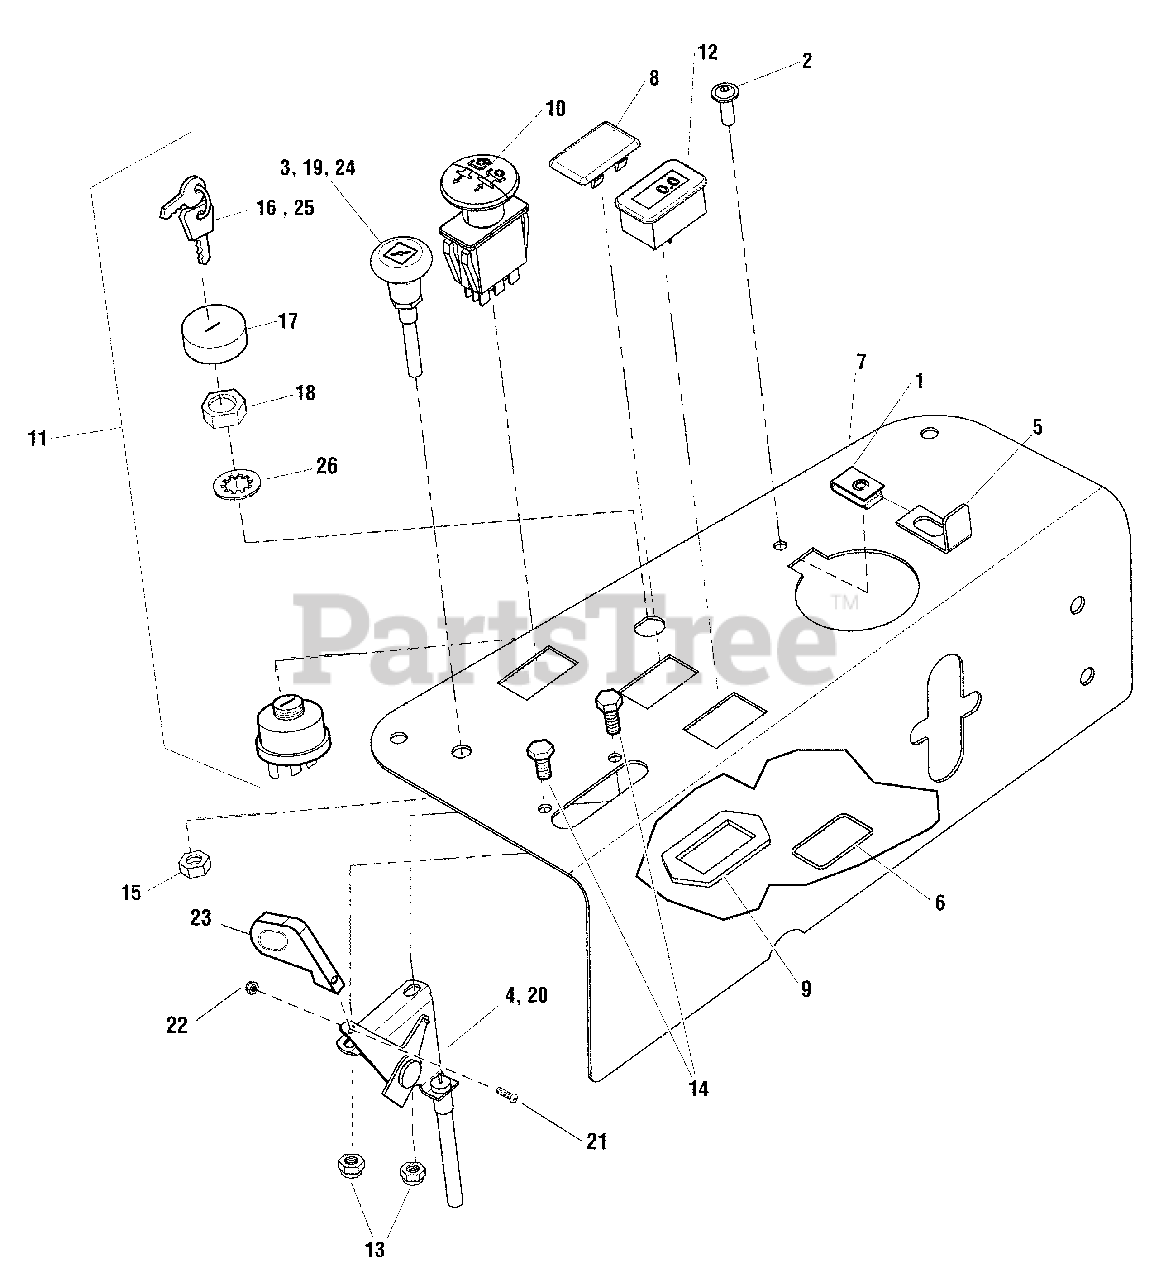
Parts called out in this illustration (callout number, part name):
1	BODY CLIP, 1/4-20 X 1/2" DEEP
2	SCREW, 1/4-20 X 3/4" ALLEN BH
3	CABLE, CHOKE CONTROL, 43.5"
4	CABLE, THROTTLE CONTROL, 36"
5	BRACKET, LOCK
6	O-RING, 7/8" ID X 1/16" W
7	PLATE, CONTROL PANEL
8	PLUG, .820X1.44 HOLE, BLACK PLASTIC
9	RING, SWITCH RETAINER
10	SWITCH, BLADE ENGAGEMENT
11	SWITCH, IGNITION, 6 POST
13	NUT, 1/4-20 HEX NYLON LOCK
14	BOLT, 1/4-20 X 3/4" GD5 YZ
15	NUT, 3/8-24 HEX
16	KEYS. BLISTER PK KIDS+MWRS DON'T MIX
17	COVER, SWITCH
18	NUT-HEX FLANGE 5/8-32 IGN SW DIE CAST
19	CABLE, CHOKE CONTROL, 30.5"\
20	CABLE, THROTTLE CONTROL, 27.5"
21	SCREW, #10-24 X 1" RS
22	NUT, #10-24 HEX NYLON LOCK
23	KNOB, THROTTLE
24	CABLE, CHOKE CONTROL, 51"
25	KEYS, BLISTER PK KIDS+MWRS DON'T MIX
26	LOCKWASHER, INTERNAL TOOTH .625 THIN BLK
